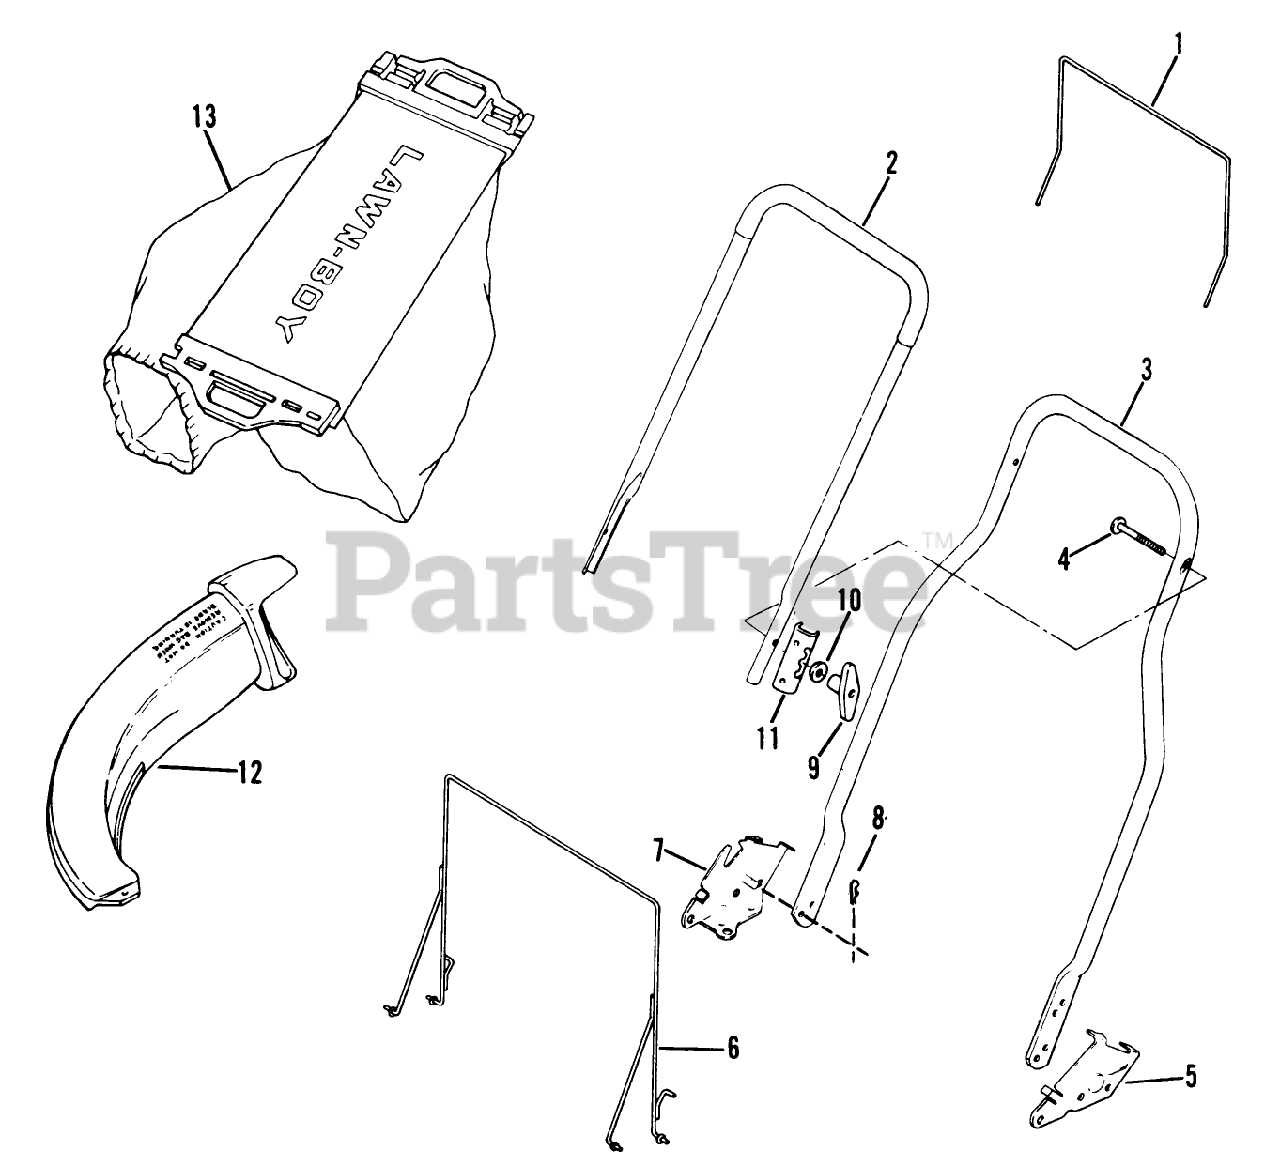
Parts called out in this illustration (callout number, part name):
1	HANGER
8	HAIR PIN
9	NUT-WING
10	WASHER-CURVED
11	BRACKET R/B 613462
